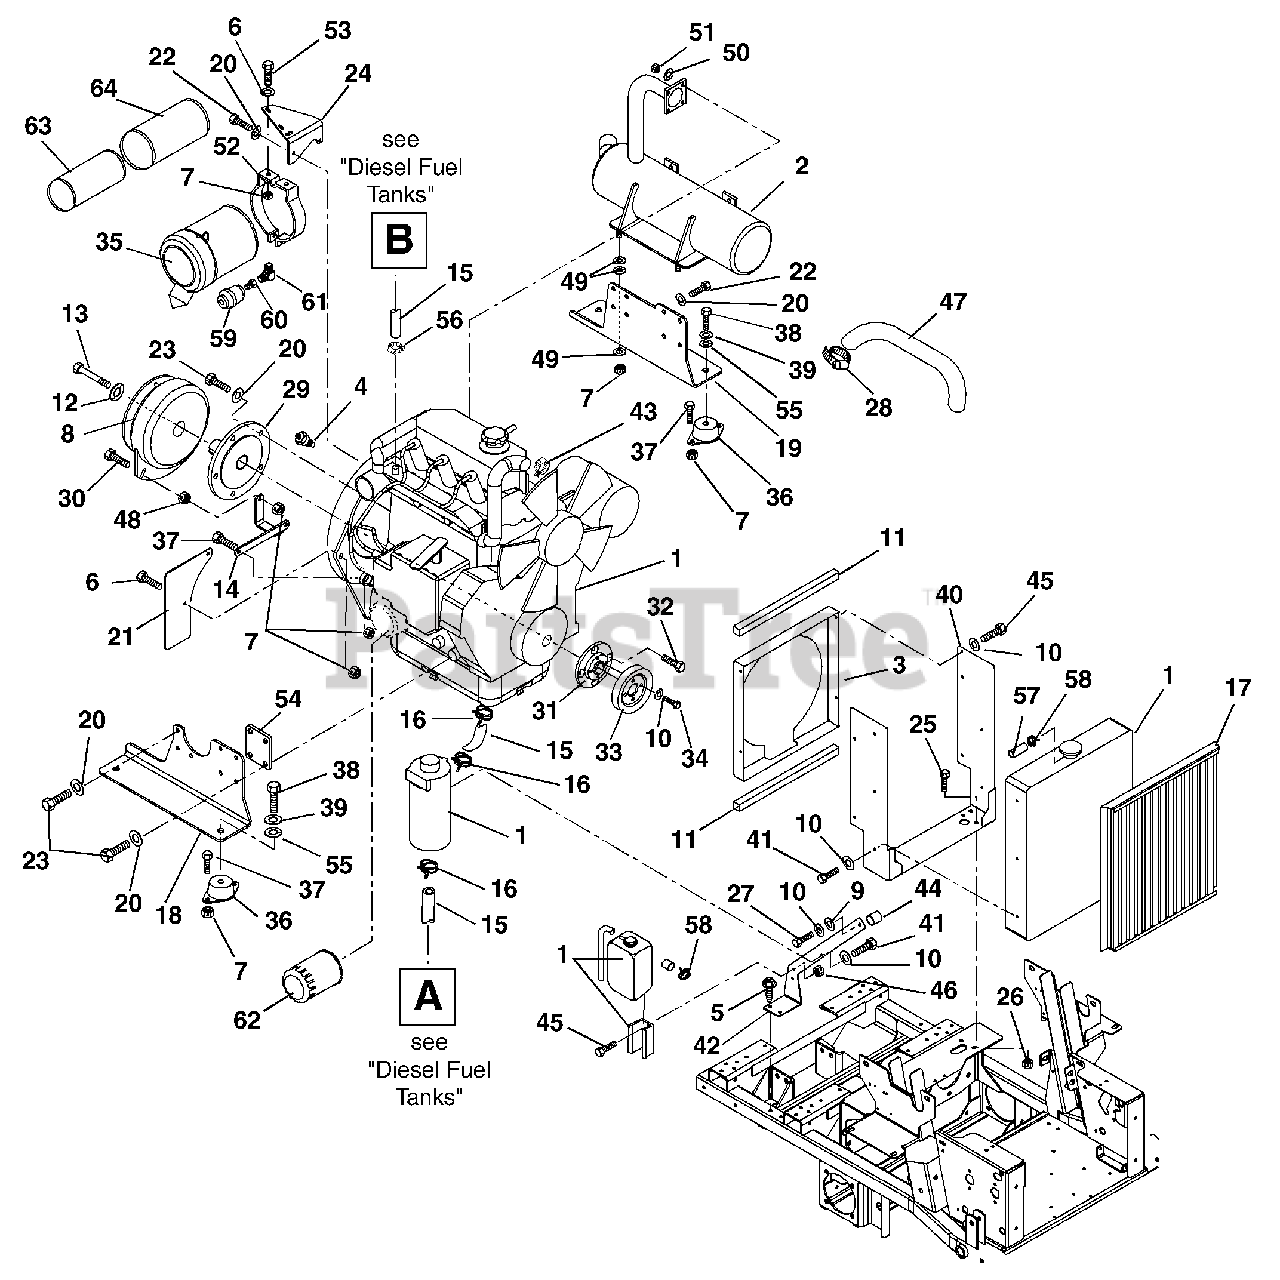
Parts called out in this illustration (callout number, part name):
1	Engine, 27HP Diesel (Daihatsu) (075, 318)
1	Engine, 31HP Diesel (Daihatsu) (076, 319)
2	Muffler (075, 318)
2	Muffler (076, 319)
3	Weldment, Radiator Shroud
4	Sender, Temperature
5	Screw, Tapping .38-16 x .75 Hex Washer Head
6	Bolt, Hex .31-18 x .75 Grade 5
7	Nut, Locking Top Flange .31-18
8	Electric Clutch
9	Washer, Flat Steel .281 x .62 x .065
10	Washer, Locking .25 x .062 Regular
11	Seal, Trim-LOK Bulk .06 Bubble
12	Washer, Locking .44 x .109
13	Bolt, Hex .44-20 x 2.50 Grade 5
14	Stabilizer, Clutch
15	Gas Line, Bulk .31" ID
16	Hose, Clamp
17	Screen, Radiator
18	Mount, Engine Right Hand
19	Mount, Engine Left Hand
20	Washer, Lock .31 x .078 Regular
21	Guard, Flywheel
22	Bolt, Hex M8-1.25 x 20
23	Bolt, Hex M8 x 1.25 x 25 Grade 8
24	Bracket, Air Cleaner
25	Bolt, Hex .38-16 x 1.00 Grade 5
26	Nut, Locking Top Flange .38-16
27	Bolt, Hex M6-1.00 x 45
28	Clamp, 2.50" Dia. Hose
29	Weldment, Stub Shaft (076, 319)
30	Bolt, Hex .31-18 x 1.50 Grade 5
31	Adapter, Sheave
32	Bolt, M8-1.25 x 25
33	Sheave, Poly-V 1.0 x 3.25
34	Bolt, Hex .25-20 x .75 Grade 5
35	Assembly, Air Cleaner
36	Mount, Engine
37	Bolt, Hex .31-18 x 1.00 Grade 5
38	Bolt, Hex .50-20 x 1.00 Grade 5
39	Washer, Locking .50 x .125 Regular
40	Bracket, Radiator Mounting
41	Bolt, Hex M6-1 x 16
42	Bracket, Overflow Mounting
43	Clamp, Hose 1.50 x .81 x 1.42
44	Spacer .328 x .76 x 1.01
45	Bolt, Hex .25-20 x .75 Grade 5
46	Nut, Locking Top Flange .25-20
47	Hose, Air Cleaner (075, 318)
47	Hose, Air Cleaner (076, 319)
48	Nut, Hex .31-18
49	Washer, Flat Steel .38 x .875 x .083
50	Washer, Locking .31 x .078 Regular
51	Nut, Hex M8-1.25
52	Bracket, Air Cleaner Mount
53	Washer, Flat Steel .38 x .875 x .083
54	Spacer, Engine Mounting
55	Washer, Flat Steel .531 x 1.06 x .095
56	Hose Clamp
57	Gas Line, Bulk .25 I.D.
58	Clamp, Hose Wire .49/.51 x .116
59	Filter Minder
60	Nipple, .125
61	Elbow,Adaptor 90 Degree, Brass, .125 x .125
62	Oil Filter
63	Element, Inner Safety
64	Element, Outer Primary
